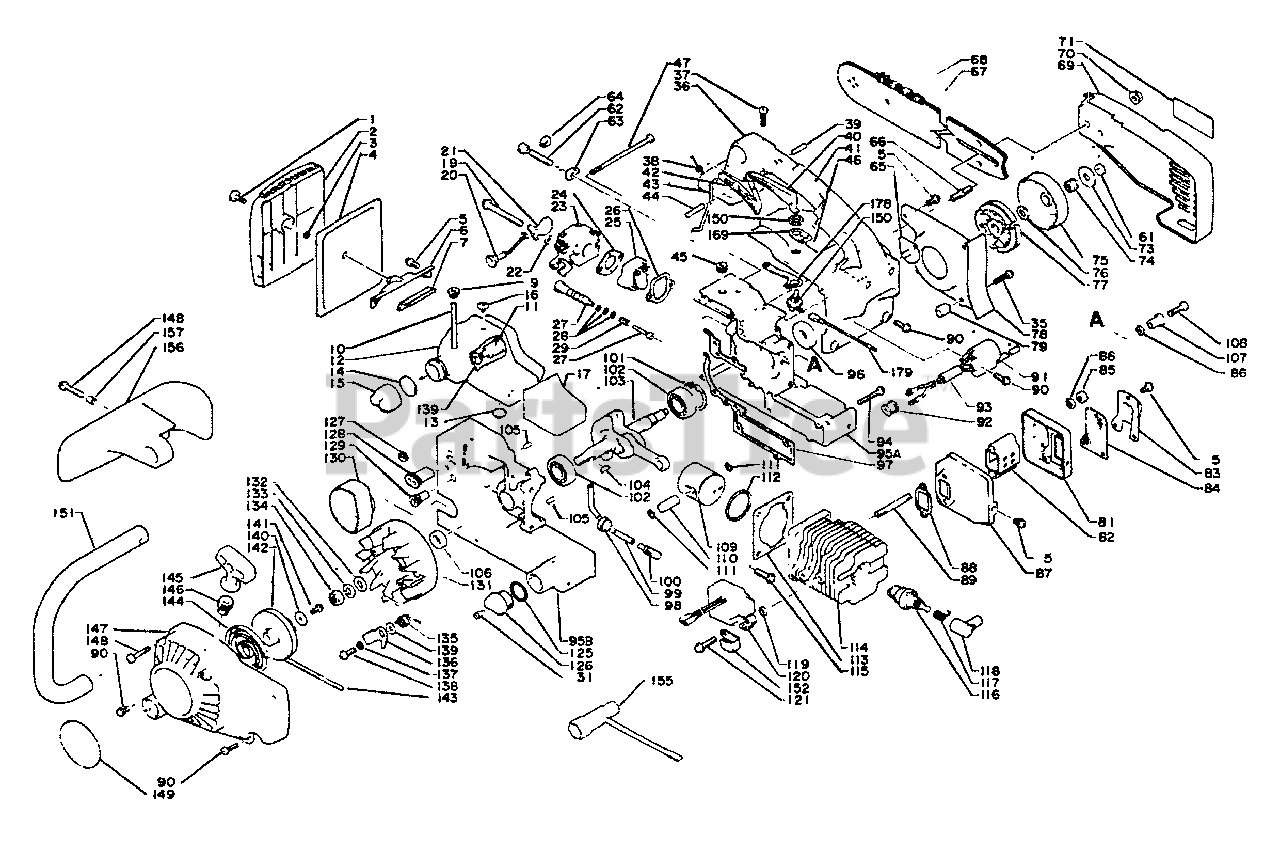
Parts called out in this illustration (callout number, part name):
1	THUMBSCREW
2	COVER, AIR FILTER
3	RING, RETAINING - 4
4	FILTER, AIR
5	SCREW - 4X10
6	BRACKET, AIR CLEANER
7	CUSHION
9	GROMMET
10	FUEL PIPE KIT
11	FILTER, FUEL
12	TANK, FUEL
14	GASKET, CAP
15	CAP
17	CUSHION
19	SCREW - 5X55
20	ROD, CHOKE
21	SHUTTER, CHOKE
22	WASHER
23	CARBURETOR C1S-K1B
24	GASKET, INTAKE
25	INSULATOR
26	GASKET, INTAKE
27	AUTO-OILER ASSY
28	O-RING - 5
31	VENT, TANK
35	SCREW - 4X20
36	HANDLE - TOP
37	SCREW - 4X18
38	SPRING
39	PIN - SPRING -- 5X18
40	LOCKOUT, THROTTLE
41	GRIP, HANDLE
42	TRIGGER, THROTTLE
43	ROD, THROTTLE
44	PIN - SPRING -- 5X25
46	LABEL
61	LOCKNUT - 6
62	SCREW, TENSIONER
63	TENSIONER, CHAIN
65	PLUG
66	STUD, GUIDE BAR
67	GUIDE BAR
68	CHAIN, SAW
69	GUARD, SPROCKET
70	NUT - 6 -- FLANGE
71	LABEL - ECHO
74	BEARING, NEEDLE
75	DRUM, CLUTCH
76	WASHER, CLUTCH
77	CLUTCH ASSY
78	PLATE, SEAL
79	SPACER
81	LID, MUFFLER
82	BAFFLE, MUFFLER
83	GUIDE, EXHAUST
84	SCREEN, SPARK ARRESTOR
85	LOCKNUT - 5
86	WASHER - 5
87	GUIDE, EXHAUST
88	GASKET, EXHAUST
90	SCREW - 4X16
91	COIL, IGNITION
94	SCREW - 4X30
95	CRANKCASE KIT
95A	CRANKCASE KIT
95B	CRANKCASE KIT
96	SEAL, OIL
97	GASKET, CRANKCASE
98	GROMMET
99	PIPE - OIL
100	FILTER, OIL
101	RING, RETAINING - 32
102	BEARING, BALL - 6201
103	CRANKSHAFT ASSY
105	PIN - LOCATING
106	SEAL, OIL
107	CATCHER, CHAIN
108	SCREW - 5X20
109	PISTON
110	PIN, PISTON
111	RING, RETAINING
112	RING, PISTON
113	GASKET, CYLINDER
114	CYLINDER
115	SCREW - 5X20
116	SPARK PLUG -- CJ-8Y
117	TERMINAL, SPARK PLUG CAP
118	CAP, SPARK PLUG
119	SPACER
120	COIL, IGNITION
121	SCREW - 5X22
125	O-RING - 16
126	CAP, OIL TANK
128	GROMMET
129	GROMMET
130	SEAL
131	FLYWHEEL
132	WASHER - 8
133	LOCKWASHER - 8
135	SPRING, RETURN
136	PAWL, STARTER
138	SCREW
139	WASHER - 5
141	SCREW - 4X10
142	REEL, ROPE
143	RePower BULK ROPE - 200 FEET
144	SPRING, REWIND
145	GRIP, STARTER
146	GUIDE, ROPE
147	CASE, STARTER
148	SCREW - 4X25
149	LABEL - ECHO
150	IGNITION SWITCH KIT
151	HANDLE - FRONT
152	CLAMP
155	T-WRENCH - 10X19mm
156	GUARD
169	LABEL - SWITCH
178	PLATE - GROUND
179	LEAD - GROUND
